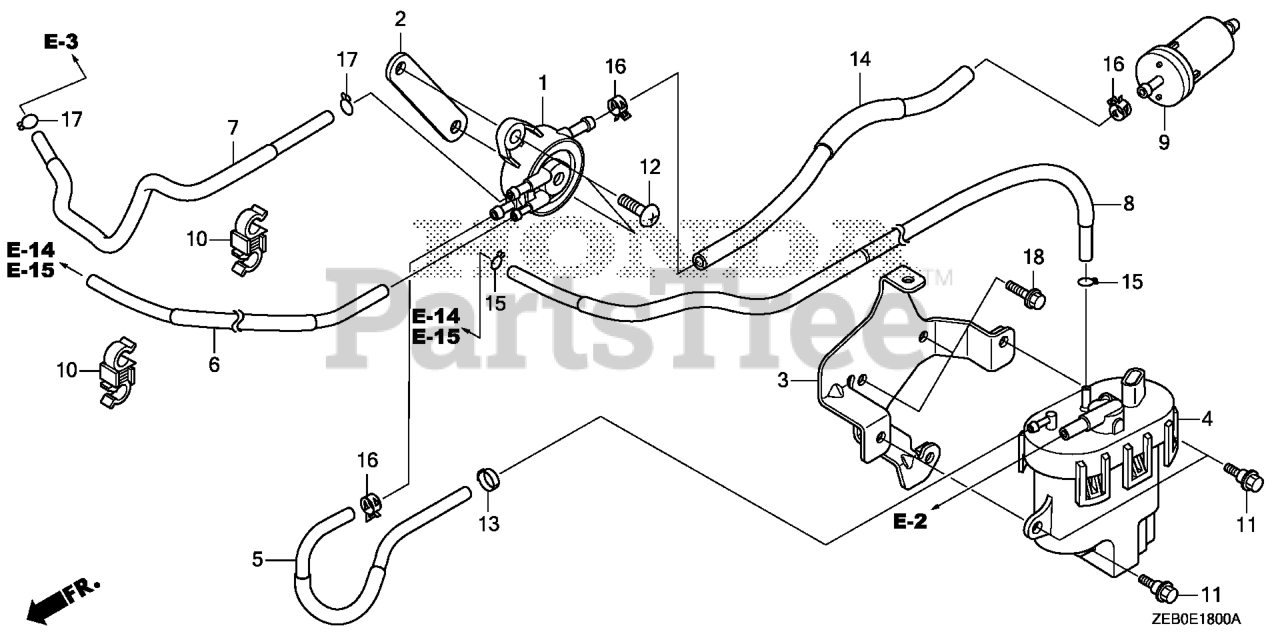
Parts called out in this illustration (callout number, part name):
1	PUMP ASSY., FUEL (MSDS)
2	STAY, FUEL PUMP
3	STAY, HIGH PRESSURE PUMP
4	PUMP ASSY., FUEL (HIGH PRESSURE)
5	TUBE B, FUEL (FKM)
6	TUBE, PURGE
7	TUBE, DIAPHRAGM
8	TUBE, VAPOR
9	FILTER, FUEL
10	CLIP, R. BRAKE WIRE
11	BOLT, SPECIAL (6X13)
12	SCREW, TRUSS (6X16)
13	CLAMP, HOSE CALKING (D12.3)
14	TUBE, FUEL (5.3X180) (FKM)
15	CLIP, TUBE (B8)
16	CLAMP, TUBE (D10)
17	CLIP, TUBE (C11)
18	BOLT, FLANGE (6X16) Use from Engine SN 2056820.
